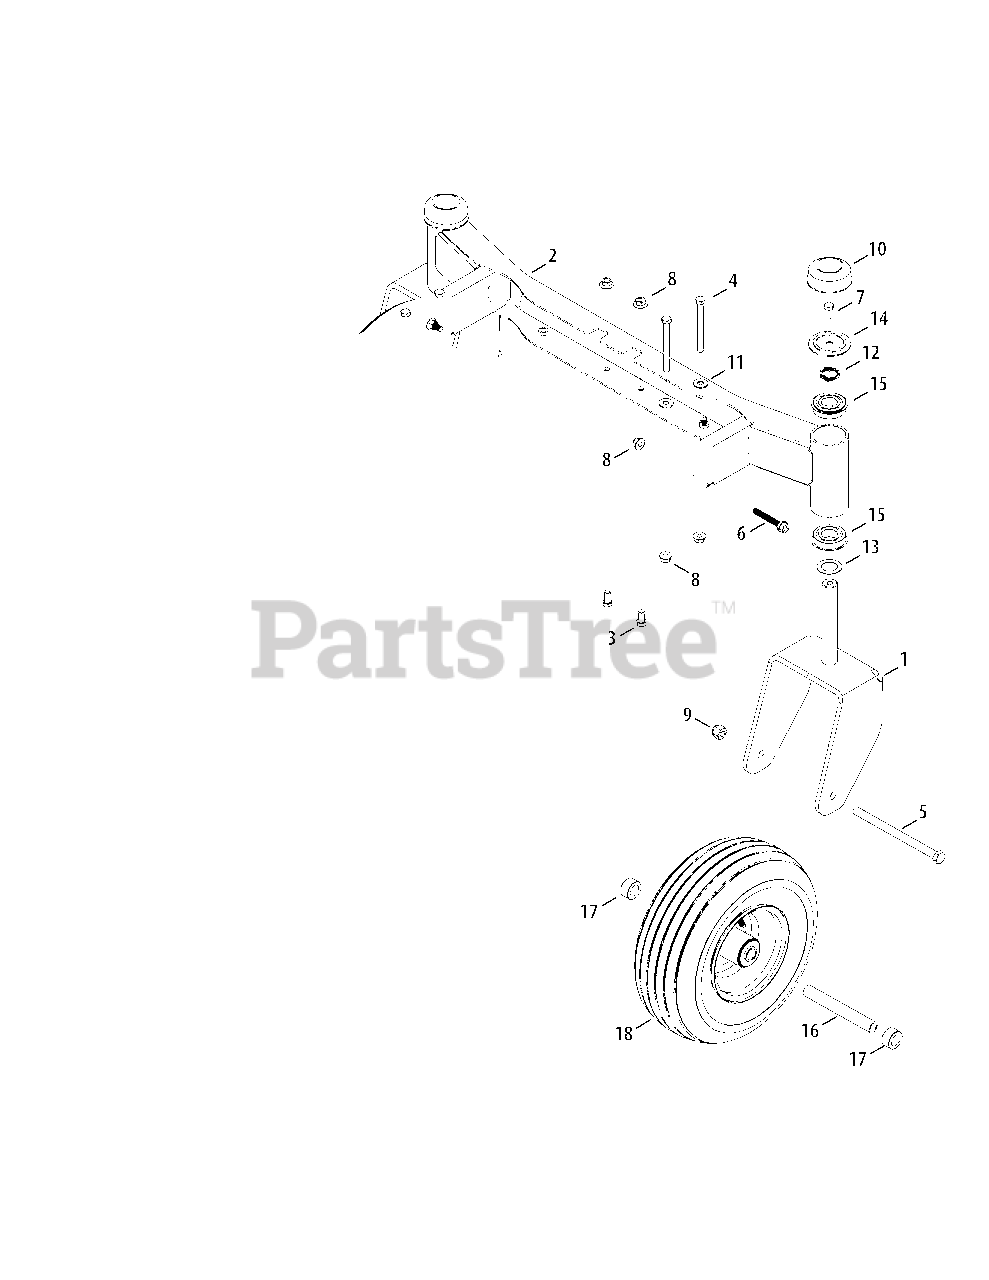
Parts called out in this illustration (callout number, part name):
1	Caster Wheel Bracket
2	Front Axle
3	Hex Cap Screw, 3/8-16 x .75
4	Hex Cap Screw, 3/8-16 x 3.75
5	Hex Cap Screw, 1/2-20 x 7.25
6	Hex Flange Screw, 3/8-16 x 2.00
7	Hex Cap Screw, 3/8-16 x .750
8	Flange Lock Nut, 3/8-16
9	Hex Lock Nut, 1/2-20
11	Flat Washer, .385 x .870 x .092
12	Wave Washer, 1.25 x 1.00 x .300
13	Flat Washer, 1.010 x 1.56 x .060
14	Shoulder Spacer, 2.50 x .200
15	Ball Bearing
16	Spacer, .51 x .75 x 5.825
17	Spacer, .76 x 1.23 x .63
18	Wheel Assembly, 13 x 5 x 6
